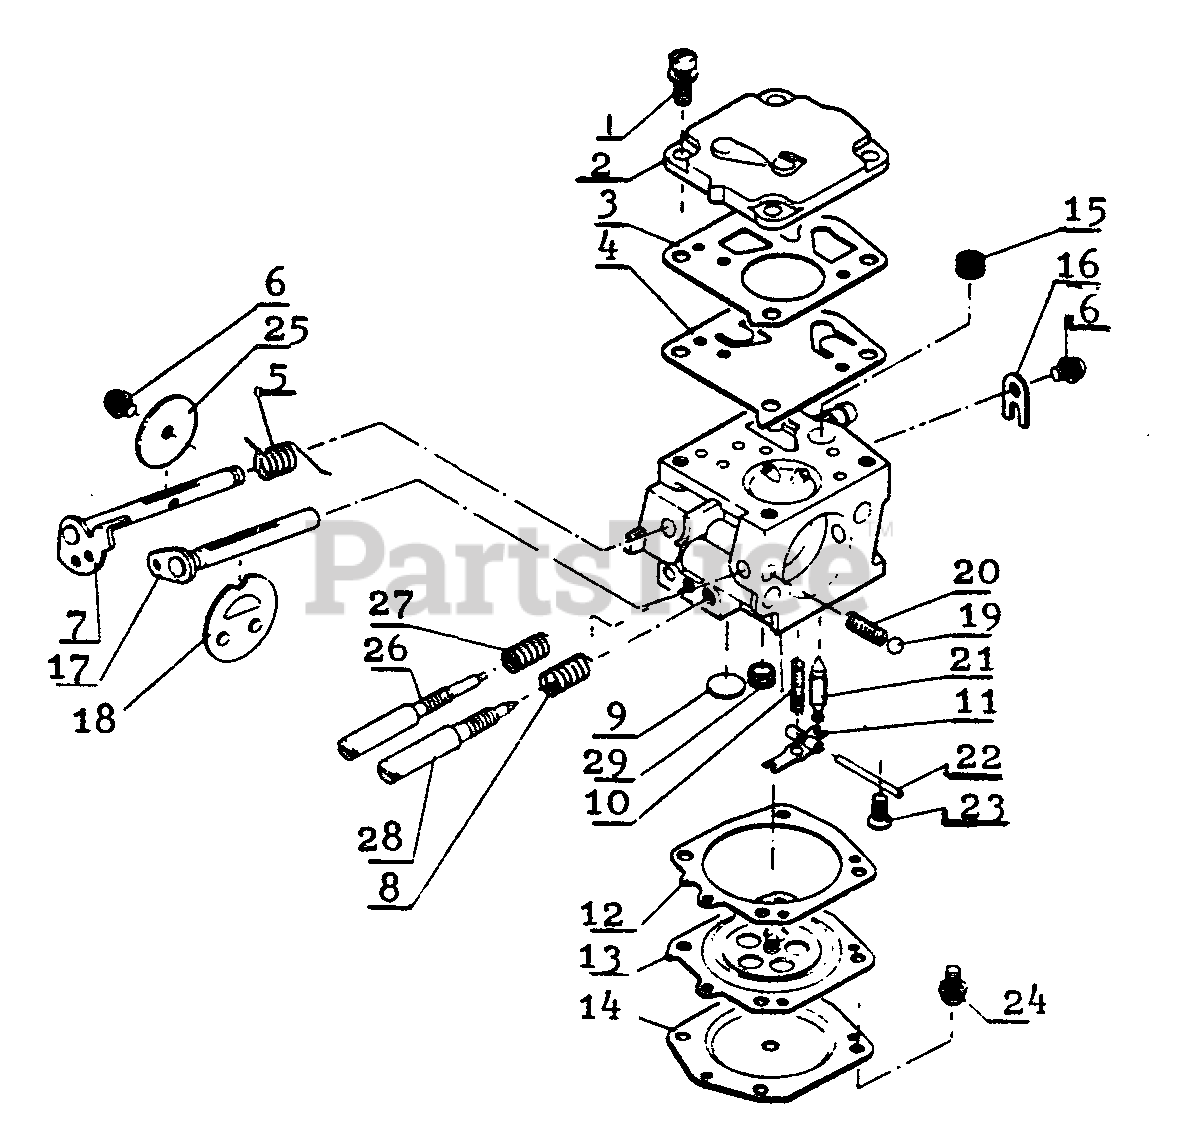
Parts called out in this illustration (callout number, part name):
1	SCREW
2	COVER, PUMP
3	GASKET, PUMP
4	DIAPHRAGM, PUMP
5	SPRING, RETURN
6	SCREW
7	SHAFT, THROTTLE
8	SPRING, IDLE ADJUST
9	PLUG, WELCH - LARGE
10	SPRING, TENSION
11	LEVER, METERING
12	GASKET, METERING DIAPHRAGM
13	DIAPHRAGM
14	COVER, DIAPHRAGM
15	FILTER, FUEL
16	CLIP, THROTTLE SHAFT
17	SHAFT, CHOKE
18	VALVE, CHOKE
19	BALL, CHOKE SET
20	SPRING, CHOKE SET
21	VALVE, INLET NEEDLE
22	PIN, METERING LEVER
23	SCREW, METERING LEVER PIN
24	SCREW
25	VALVE, THROTTLE
26	SCREW, IDLE ADJUST
27	SCREW, IDLE ADJUST
28	SCREW, MAIN ADJUST
29	VALVE, CHECK
